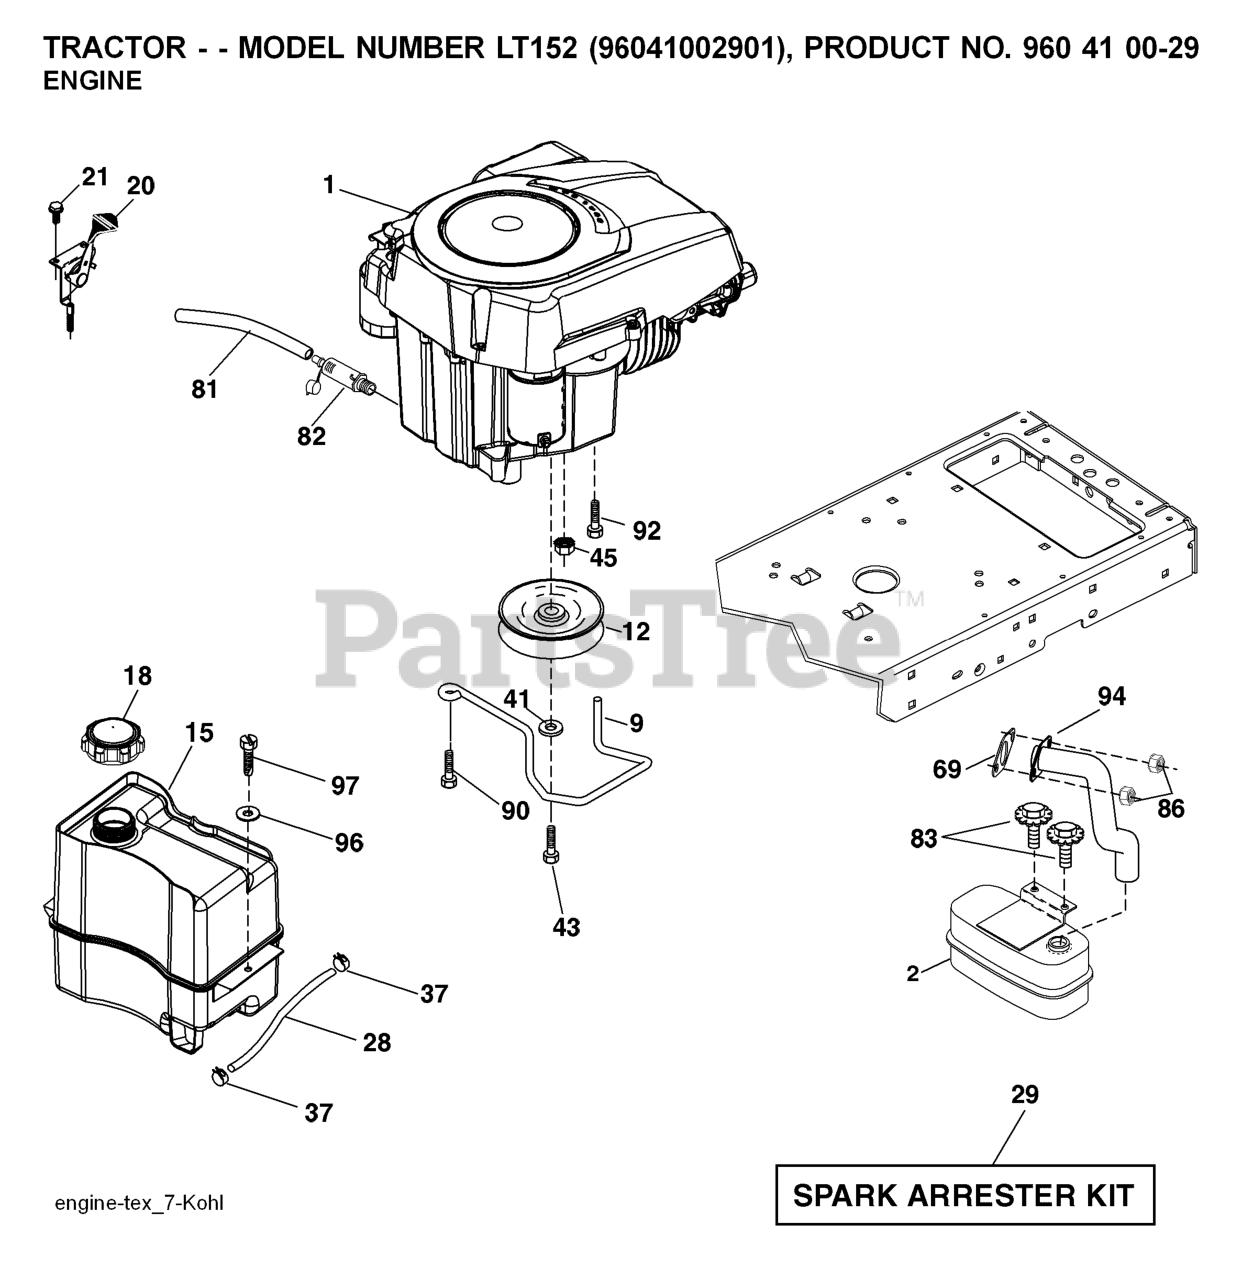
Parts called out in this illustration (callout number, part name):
2	MUFFLER.SINGLE.CYL.KOHL/B&S
9	KEEPER.BELT.ENGINE.3.25 (3 2)
12	PULLEY ENGINE
15	RP TANK FUEL FRT 1.5 GAL
18	FUEL CAP
20	CONTROL.TH/CK.C.
21	SCREW
28	LINE.FUEL.20
29	KIT.SPARK ARRESTOR 794945 B&S
37	HOSE CLAMP
41	LOCKWASHER
43	BOLT HEX 7/16-20X4-1/4"
45	NUT
81	TUBE, DRAIN OIL ASM.
82	PLUG DRAIN OIL EASY
83	BOLT.5/16-18UNCX3/4 W/SEMS.BLK
86	NUT.HEX.FLANGE.TOPLOCK
90	SCREW 3/8-16X1
92	SCREW 3/8-16X1
94	RP.TUBE.EXHAUST.KOHL.COURAGE
97	SCREW HEXWSHR 1/4-20X3/4
